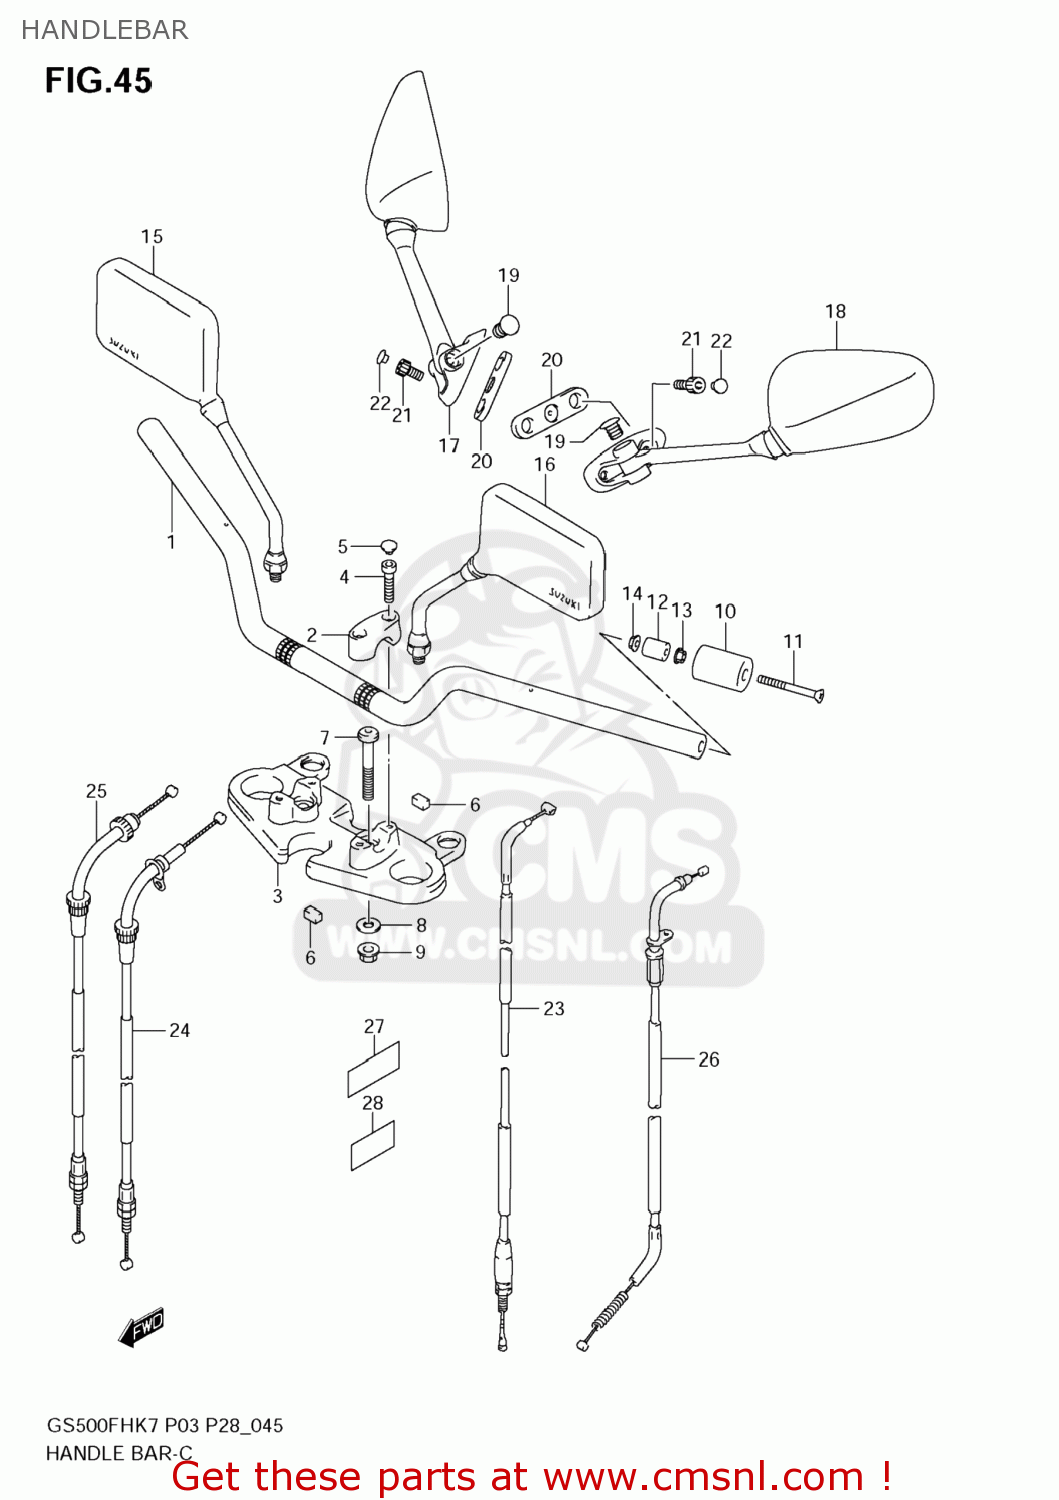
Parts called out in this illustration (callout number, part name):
1	HANDLEBAR
2	HOLDER,UPPER
3	HOLDER, LOWER
4	BOLT
5	CAP(OD:11)
6	CUSHION,HANDLE HOLDER
7	BOLT
8	WASHER
9	NUT
10	BALANCER SET,H
11	SCREW
12	EXPANDER,HANDLE BALANCER
13	NUT
14	NUT
15	MIRROR ASSY,RR VIEW,R
16	MIRROR ASSY,RR VIEW,L
17	MIRROR ASSY,RR VIEW,R
18	MIRROR ASSY,RR VIEW,L
19	CAP(OD:14)
20	CUSHION,RR VIEW MIRRORR
21	BOLT 6X16
22	CAP(OD:10)
23	CABLE ASSY,CLUTCH
24	CABLE ASSY,THROTTLE NO.1
25	CABLE ASSY,THROTTLE NO.2
26	CABLE,STARTER
27	PROTECTOR, CABLE
28	PROTECTOR, CABLE NO. 2
